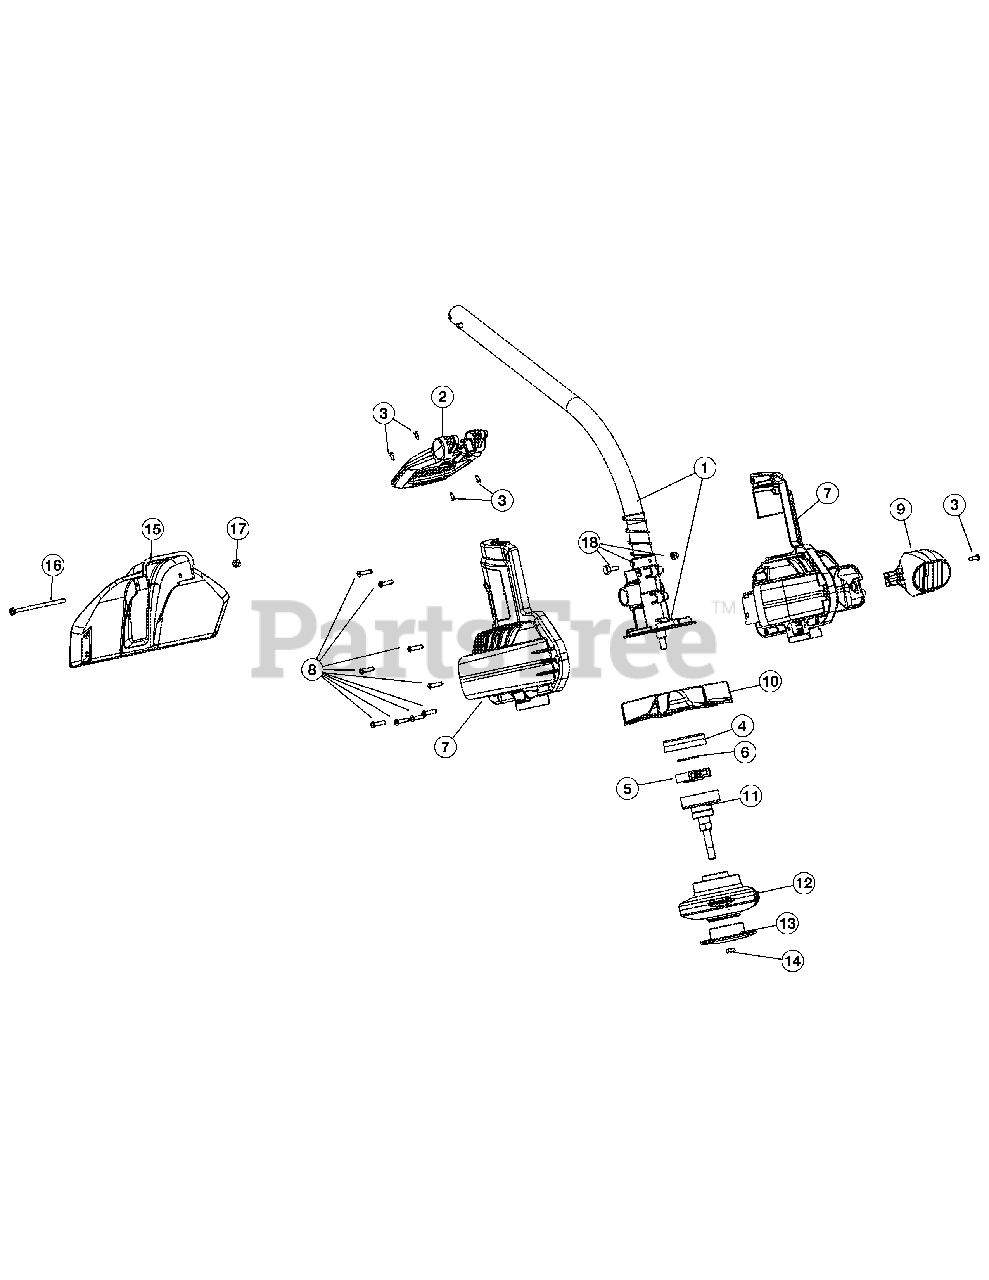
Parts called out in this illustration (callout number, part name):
1	Lower Drive Shaft Housing Assembly (includes 18)
2	Shift Handle Assembly (includes 3)
3	Screw
4	Clutch Drum Container
5	Clutch Assembly
6	Washer
7	Housing Assembly (includes 8)
8	Screw
11	Clutch Drum Assembly w/Spool Shaft
12	Fixed Line Head (includes 13 & 14)
13	Glide Cap
14	Locknut
15	Guard Assembly w/Blade (includes 16 & 17)
16	Screw
17	Nut
